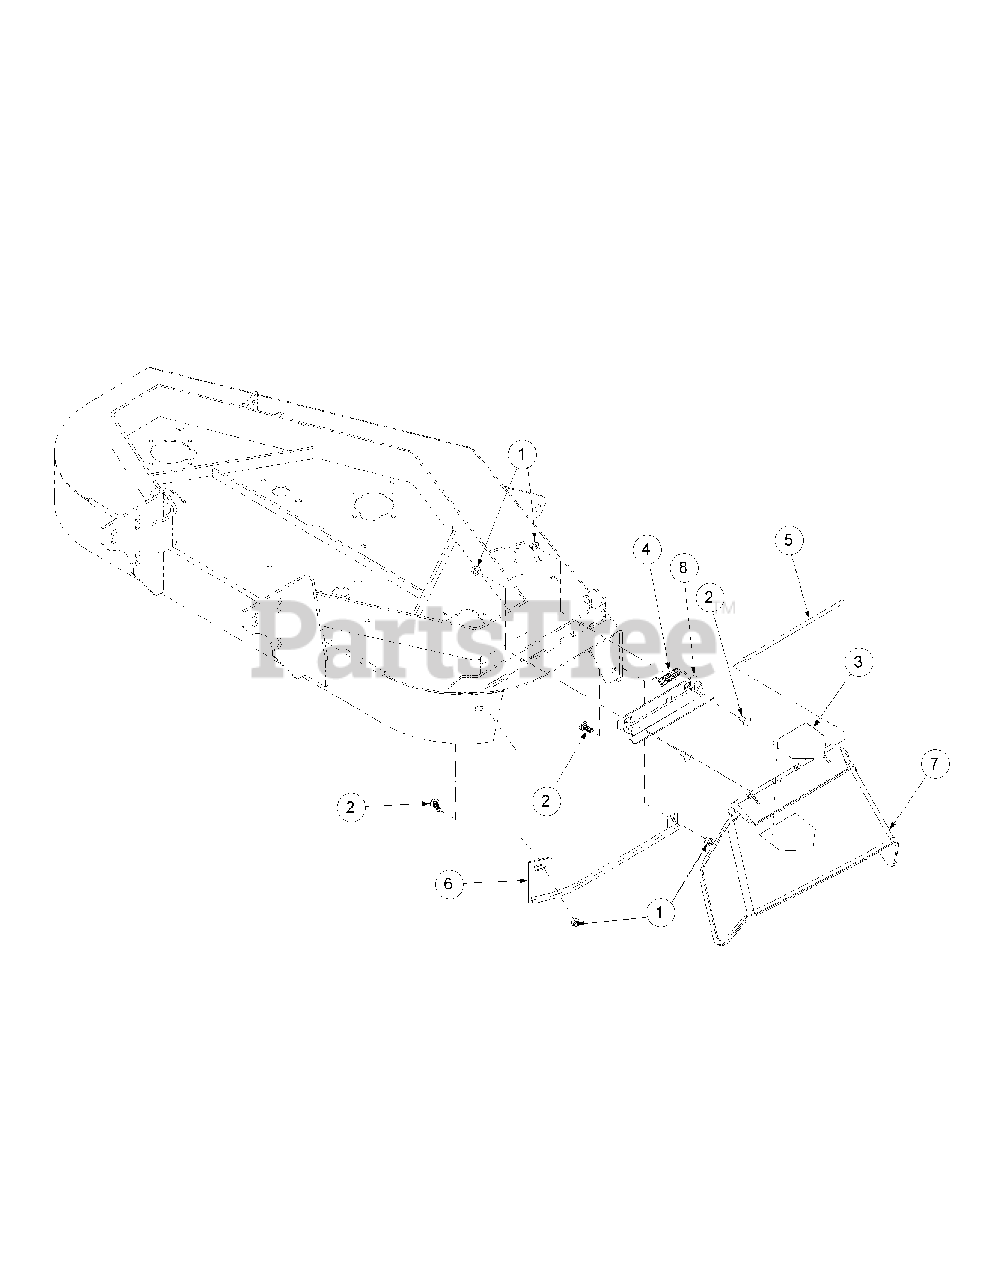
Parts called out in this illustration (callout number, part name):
1	Nut, Hex Flange Lock, 3/8-16
2	Carriage Bolt, 3/8-16 x .75
3	Decal, Danger, Hands & Feet
4	Torsion Spring, 0.4 ID x 2.16
5	Chute Deflector Rod
6	Stiffner Assembly, 52"
7	Chute Deflector
8	Chute Deflector Bracket
